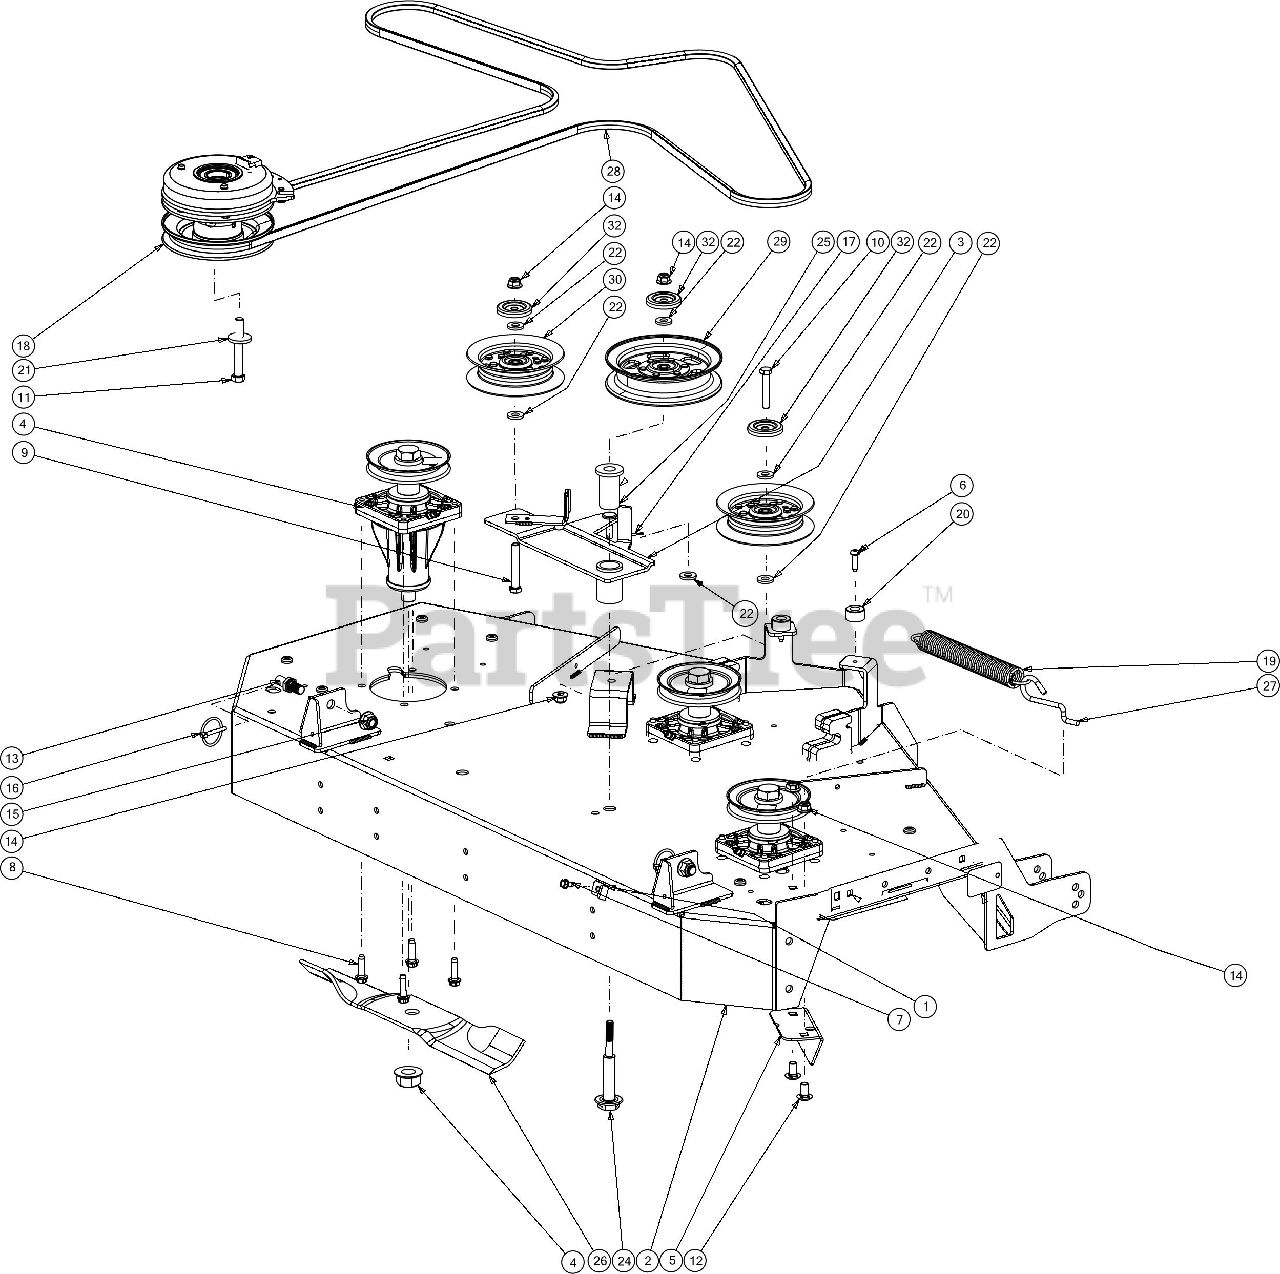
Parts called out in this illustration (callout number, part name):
1	HOOK RETAIN BRACKET
2	48" FAB DECK SHELL
3	48" DECK IDLER ASSEMBLY
4	SPINDLE ASSEMBLY
5	DECK CHUTE BAFFLE
6	SCREW 1/4-20 X 1.0
7	SCREW 1/4-20 X.500
8	SCREW 5/16-18 X 1.25
9	HEX SCREW-3/8-16X2.5 GR5
10	SCREW 3/8-16 X 2.0 GR5
11	SCREW 7/16-20 x 3.25 GR5
12	CARRIAGE BOLT 3/8-16 x .75
13	DECK PIN
17	COTTER PIN 3/32
18	ELECTRIC PTO CLUTCH
19	EXTENSION SPRING
21	FLAT WASHER .445 X 1.248 X .170
22	FLAT WASHER
24	SHOULDER BOLT
25	SHOULDER SPACER
26	17" BLADE (HI LIFT)
26	Cub Cadet 48" HI LIFT BLADE SET
26	17" HI-LIFT BLADE 0.756 ID
26	LOW-LIFT 17" BLADE (48"DECK)
26	BLADE-HI LIFT 17.0
26	17" BLADE (MULCH)
27	DECK SPRING HOOK
28	DECK BELT A SEC X 137"
28	Cub Cadet 48"Z-FORCEDECK BELT (05012)
29	IDLER PULLEY 5.0
30	IDLER PULLEY 4.0
32	IDLER PULLEY CAP
